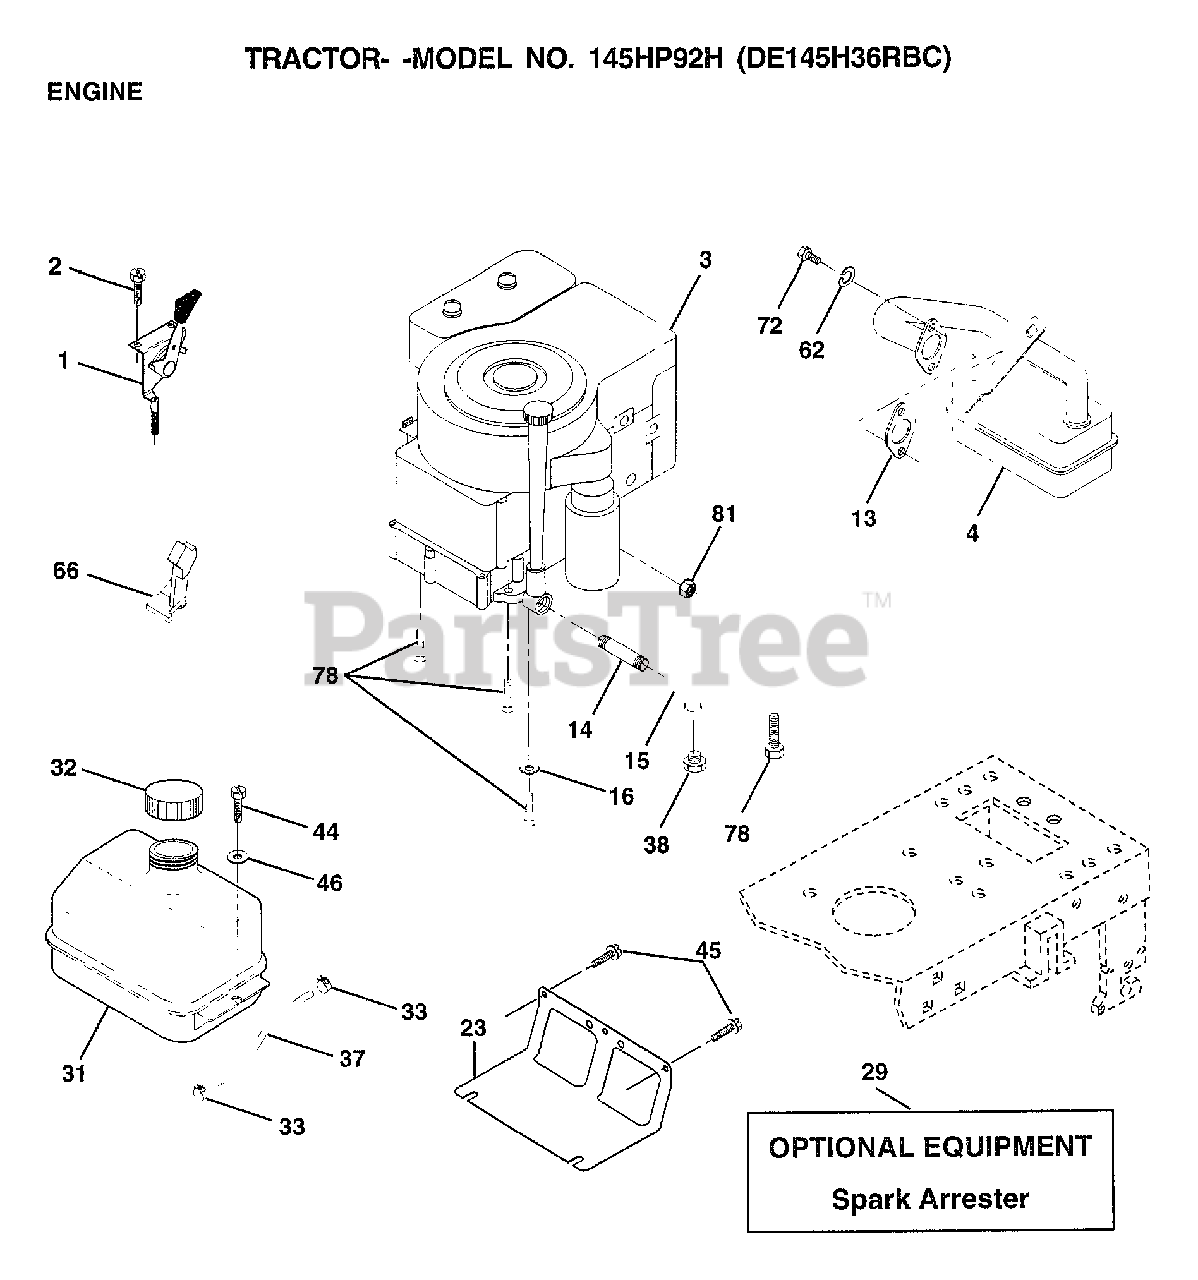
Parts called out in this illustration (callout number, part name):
1	CONTROL.THTL.23.5
2	SCREW LT
4	MUFFLER
14	PIPE NIPPLE
15	ELBOW
16	LOCKWASHER
23	SHIELD BROWNING
31	TANK.FUEL.LT.
32	CAP ASM FUEL
33	HOSE CLAMP
37	LINE FUEL
44	SCREW
45	SCREW
46	WASHER
62	LOCKWASHER
66	"STOP,DASH THROTT"
72	SCREW
78	SCREW
81	NUT
